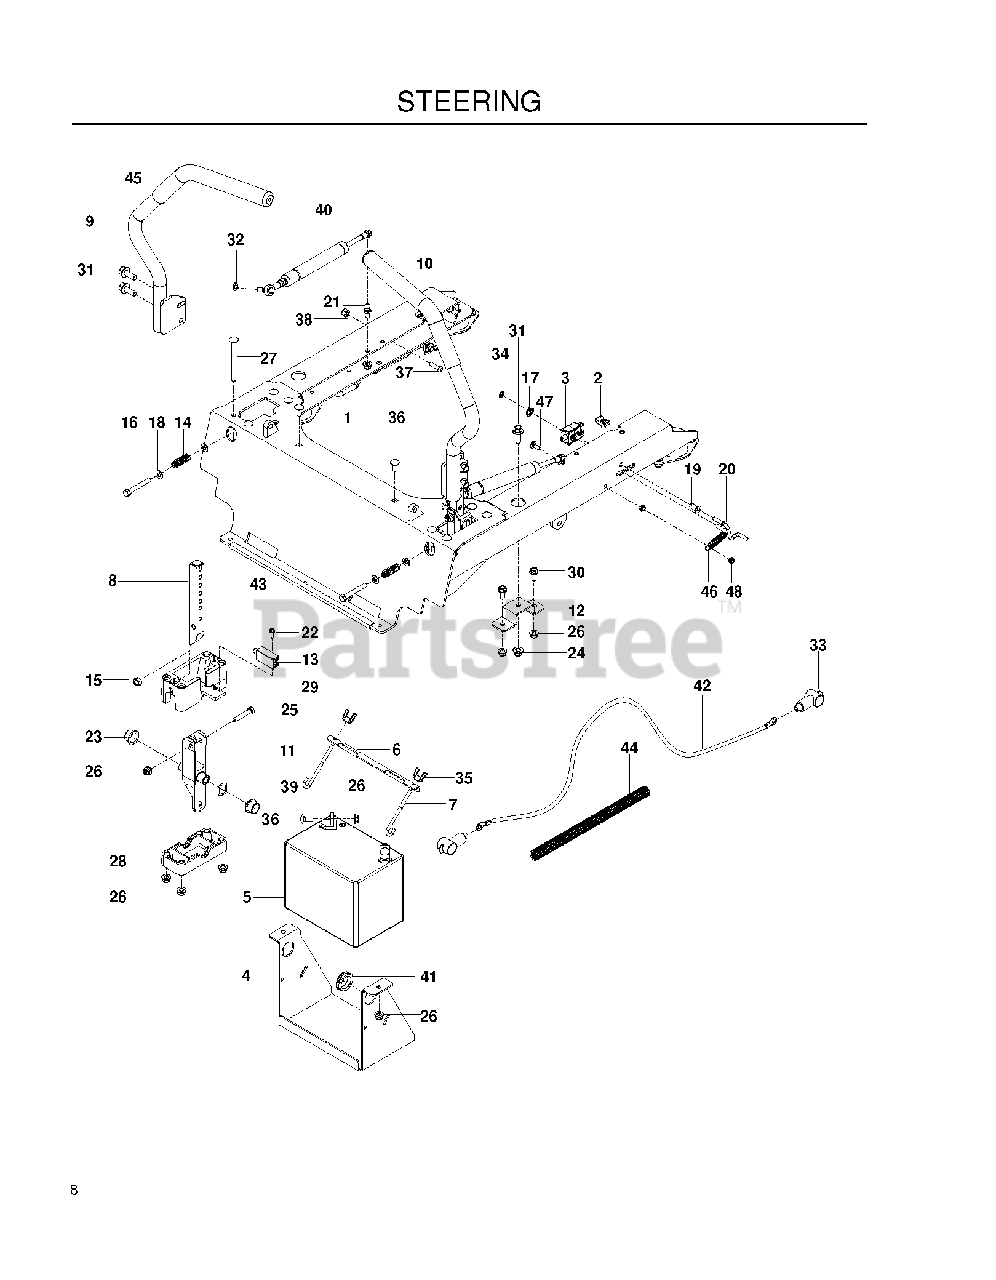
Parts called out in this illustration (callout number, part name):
1	FRAME, SEAT MOUNT, BLUE
2	U-CLIP 5/16-18 NUT RETAINER
3	SWITCH, BRAKE 3P
4	BRACKET, BATTERY, BLK
5	BATTERY, 12 V 330 AMP TBR
6	BRACKET, BATTERY MOUNT
7	HOOK, "J"
8	LEVER, MOTION
9	LEVER, W/GRIP, RT
10	LEVER, W/GRIP, LT
11	LEVER, CONTROL
12	MOUNT, MID-SECTION, BLK
13	SWITCH, INTERLOCK
15	NUT 5/16C HEX
16	HCS 5/16-18 X 2 1/2 TPBLT
17	BOLT RETAINER 3/8
18	FLAT WASHER 5/16 SAE
19	BUSHING, 1/4 FLANGE
20	LINK, SWITCH
21	STUD.BALL.10MM
22	SCREW #10 X 1/2 SELF TAPPING
23	BEARING, FLANGE
25	HCS 5/16C X 1 3/4
26	5/16-18 NYLOC FLANGE NUT
27	RHSNB 5/16-18 X 3-3/4 GR 5 ZD
28	BLOCK, LOWER
29	BLOCK, UPPER
30	HHFS 5/16-18 X 3/4
31	HHFS 3/8-16 X 1 GRD 5 ZD
32	WASHER 5/16 LOCK
33	INSULATOR
34	NUT PUSH
35	WING NUT 1/4
36	BOLT 5/16C X 3/4" CARRIAGE
37	SCR #10-24 X .75 SKT HD BLK
38	NUT 10-24 NYLOC
39	WASHER, .825 X 1.087, WAVE
40	ASSEMBLY, DAMPENER
41	RUBBER GROMMET
42	CABLE, POSITIVE, 55"
43	Flex Trim, 1' Black
44	LOOM, SPLIT, CONVOLUTED
45	GRIP - DRIVE LEVER
46	SPRING, EXTENSION
47	RHSNB 1/4C X 3/4
48	JAM NUT 1/4C
